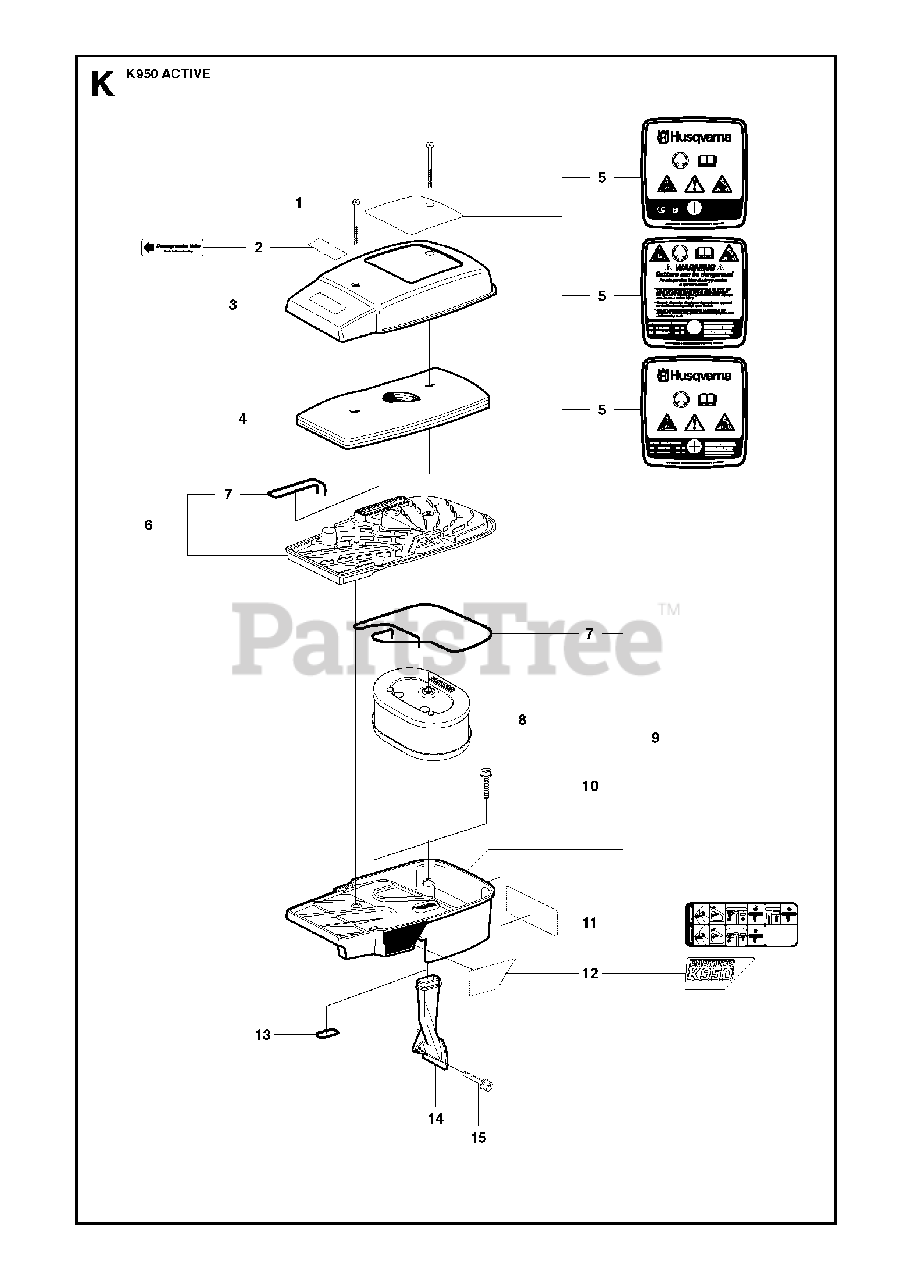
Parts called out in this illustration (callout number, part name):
3	COVER
5	LABELEPA USA
5	LABELEPA Canada
6	FILTER BOTTOMIncl. 7
9	CYLINDER COVER ASSYIncl. 7, 10, 11, 12
10	SCREW IHSCFM
12	LABEL
15	SCREW IHSCFM
